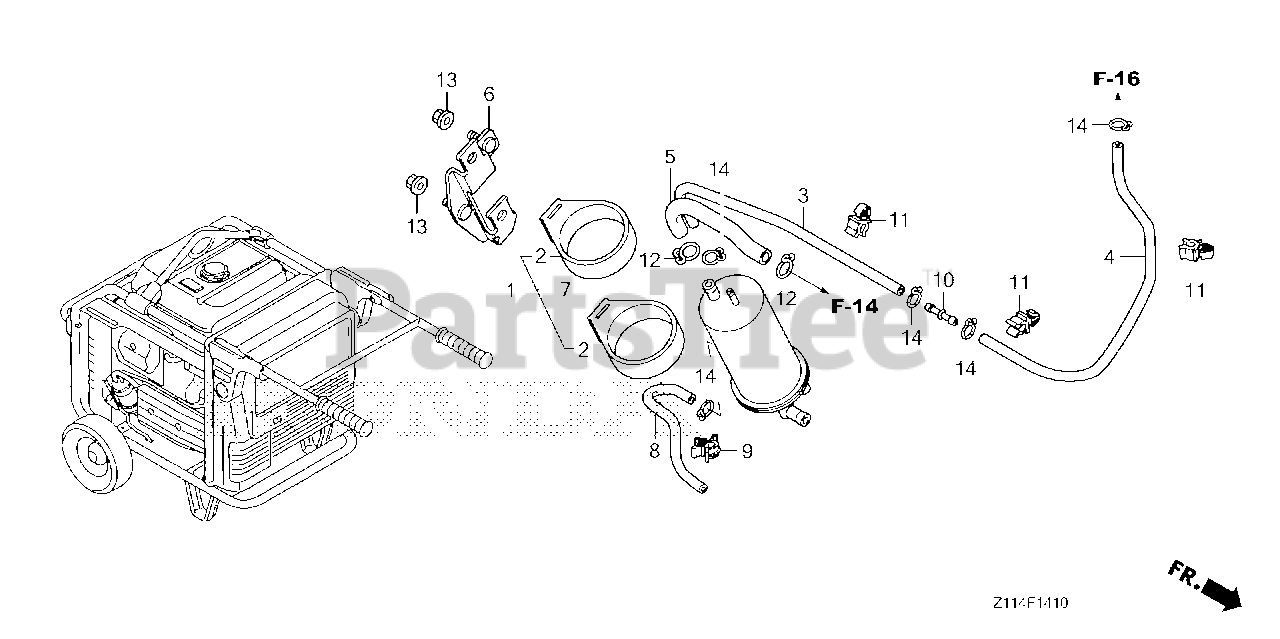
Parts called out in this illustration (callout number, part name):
1	CANISTER ASSY.
2	RUBBER, CANISTER MOUNTING
3	TUBE A, CANISTER CHARGE
4	TUBE B, CANISTER CHARGE
5	TUBE, CANISTER PURGE
6	STAY, CANISTER
7	CANISTER ASSY.
8	TUBE, CANISTER DRAIN
9	CLIP, WIRE HARNESS
10	JOINT B, WASHER TUBE (MITSUBA)
11	CLIP, TUBE
12	CLIP, TUBE
13	NUT, FLANGE (6MM)
14	CLIP, TUBE (B7)
